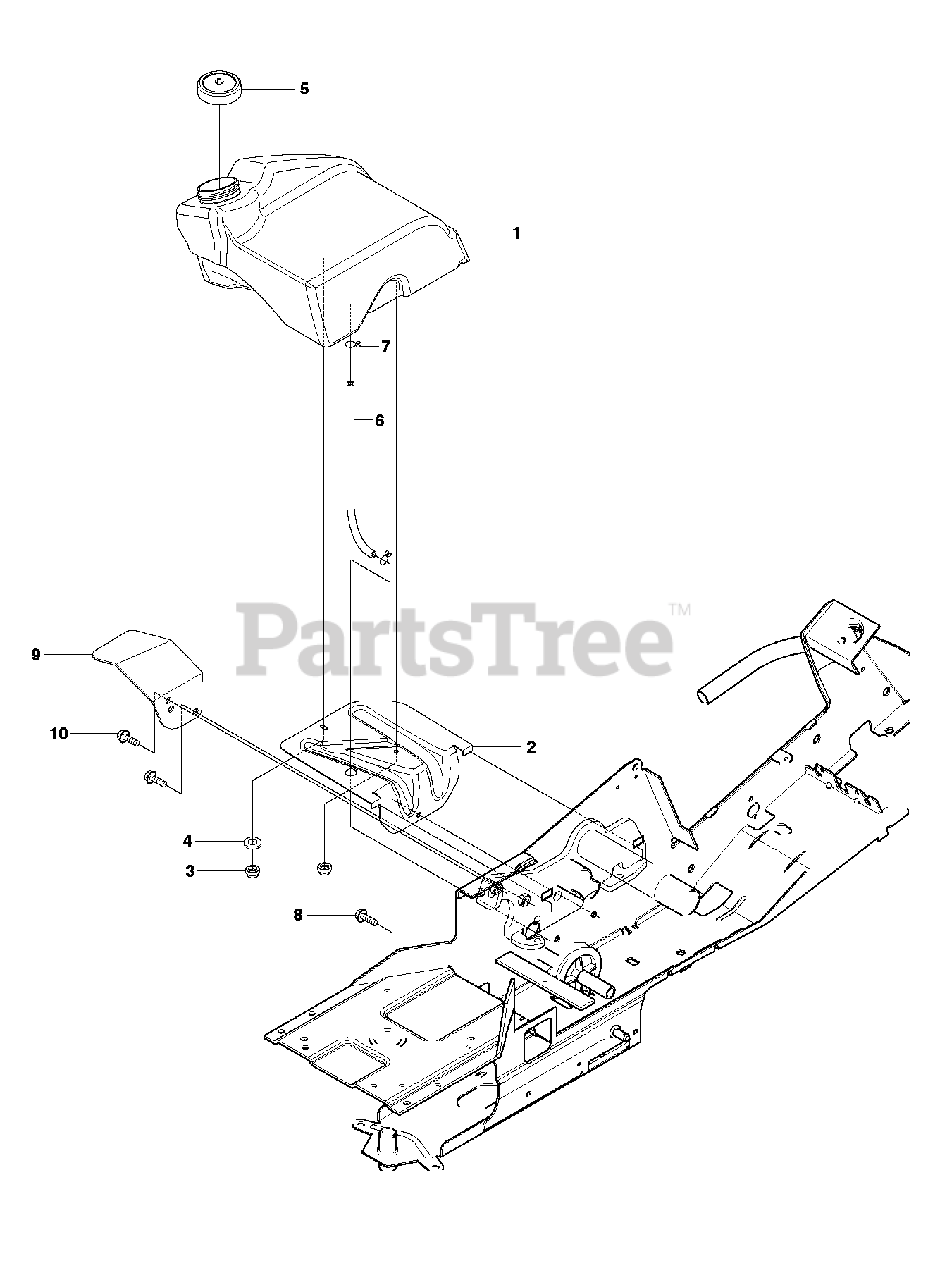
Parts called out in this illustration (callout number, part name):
3	LOCKNUT M6
4	WASHER
10	SCREW M10X25
